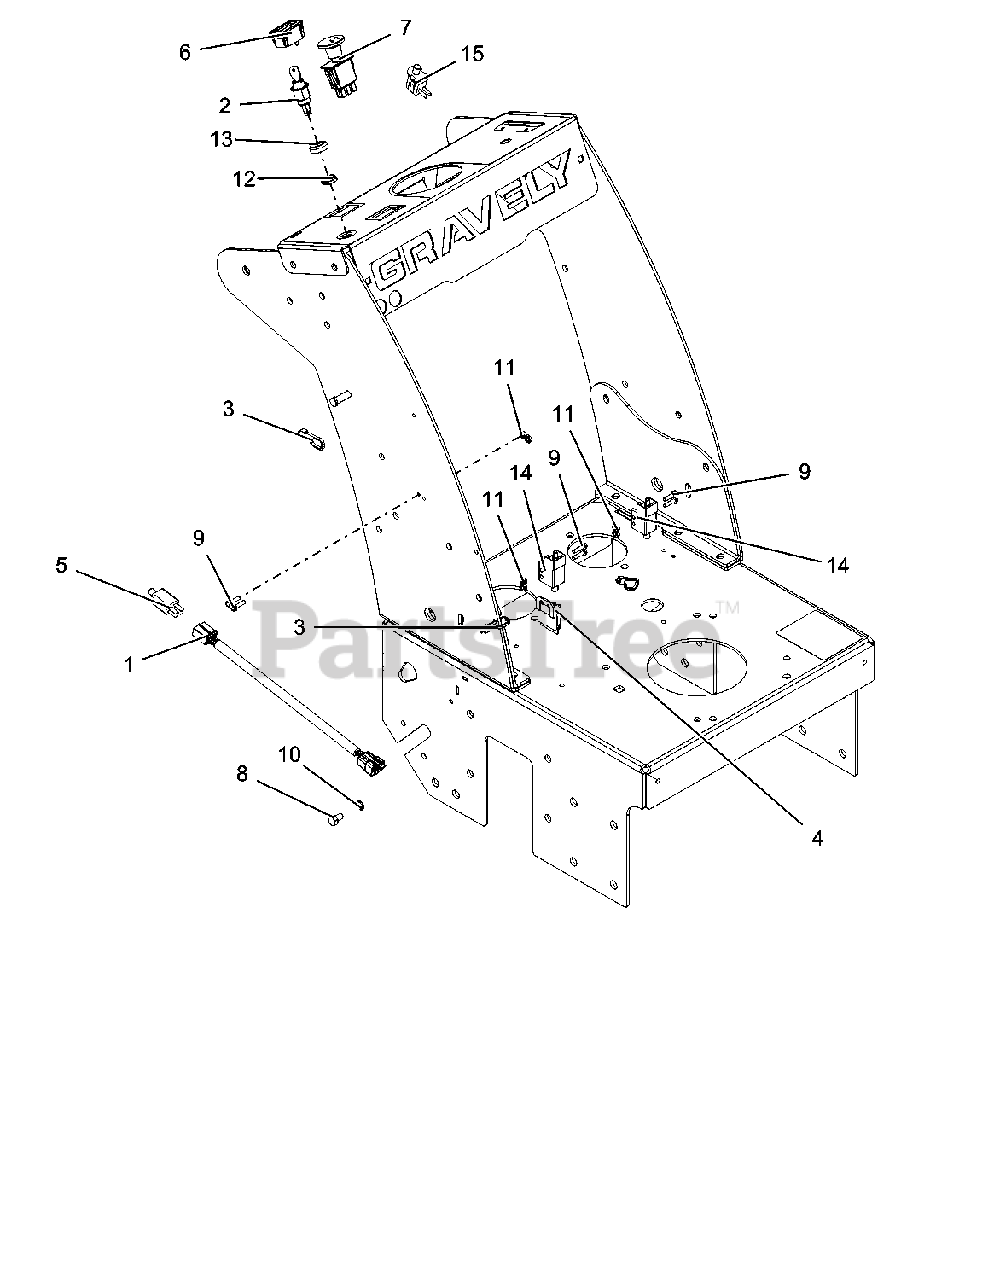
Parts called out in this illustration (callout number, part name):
1	HARNESS, JUMPER BRAKE SWITCH
2	SWITCH, TWO POSITION KEY
3	CABLE TIE, .15 X 8.50
4	MODULE, ELECTRONIC
5	SWITCH- DOUBLE POLE N.O./N.O.
6	METER, HOUR INDCTV RECOIL ENG
7	SWITCH, CLUTCH (WITH GRAPHIC)
8	@BLT-HEX M8 X 1.25X14 YWZC
9	@SCR-MCH 10-24X.75 HWH YWZC
10	WSHR-LK-EXT .326X.599X.031 YWZC REV
11	NUT-KEPS 10-24
12	NUT-PANEL .625-32 GRECO REV
13	CAP, IGNITION SWITCH
14	SWITCH, INTERLOCK REV C
15	SWITCH, SEAT OVERIDE (N.O.)
